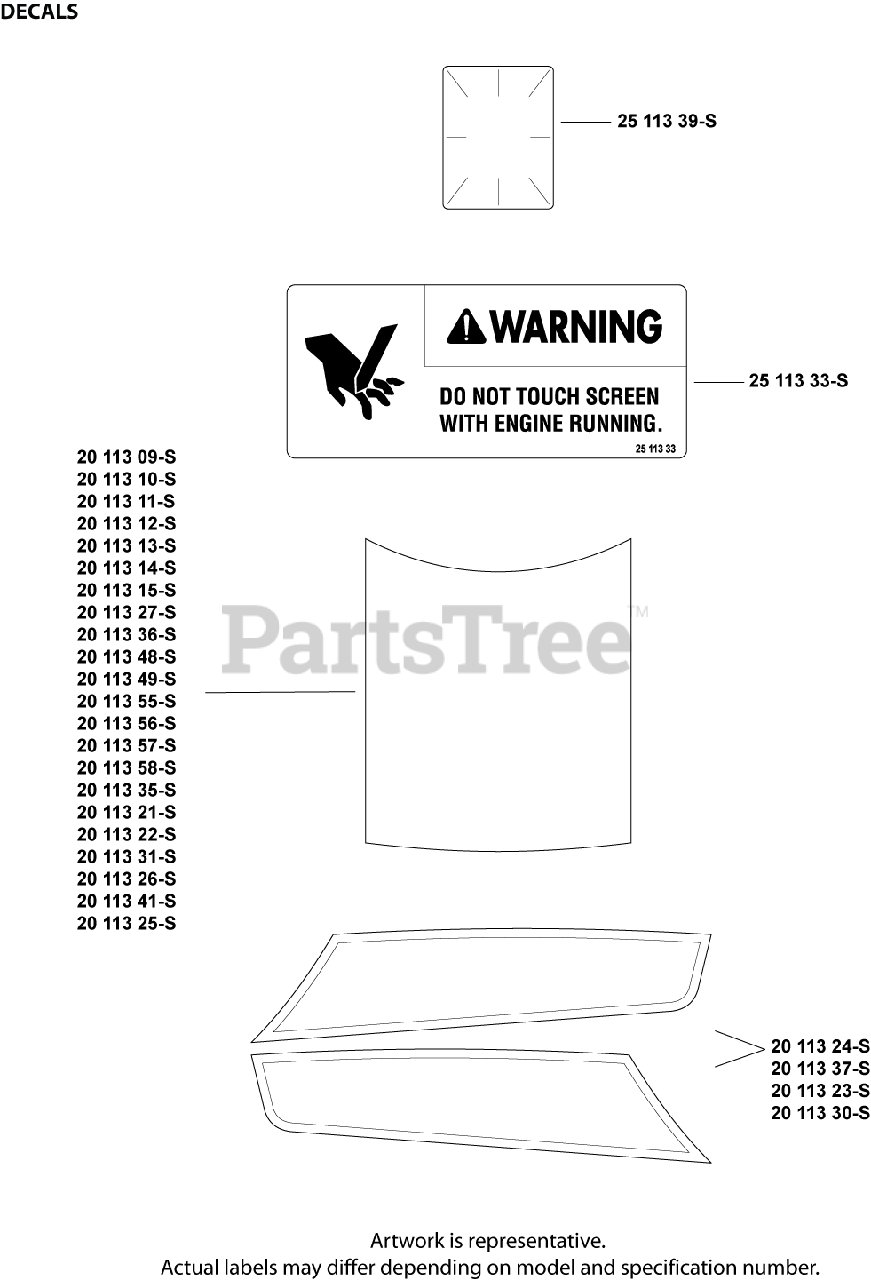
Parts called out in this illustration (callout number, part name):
1	DECAL, CLEAR LAMINATE USE 25 113 70-S
2	LABEL - USE 20 113 62-S
3	LABEL - USE 20 113 70-S
